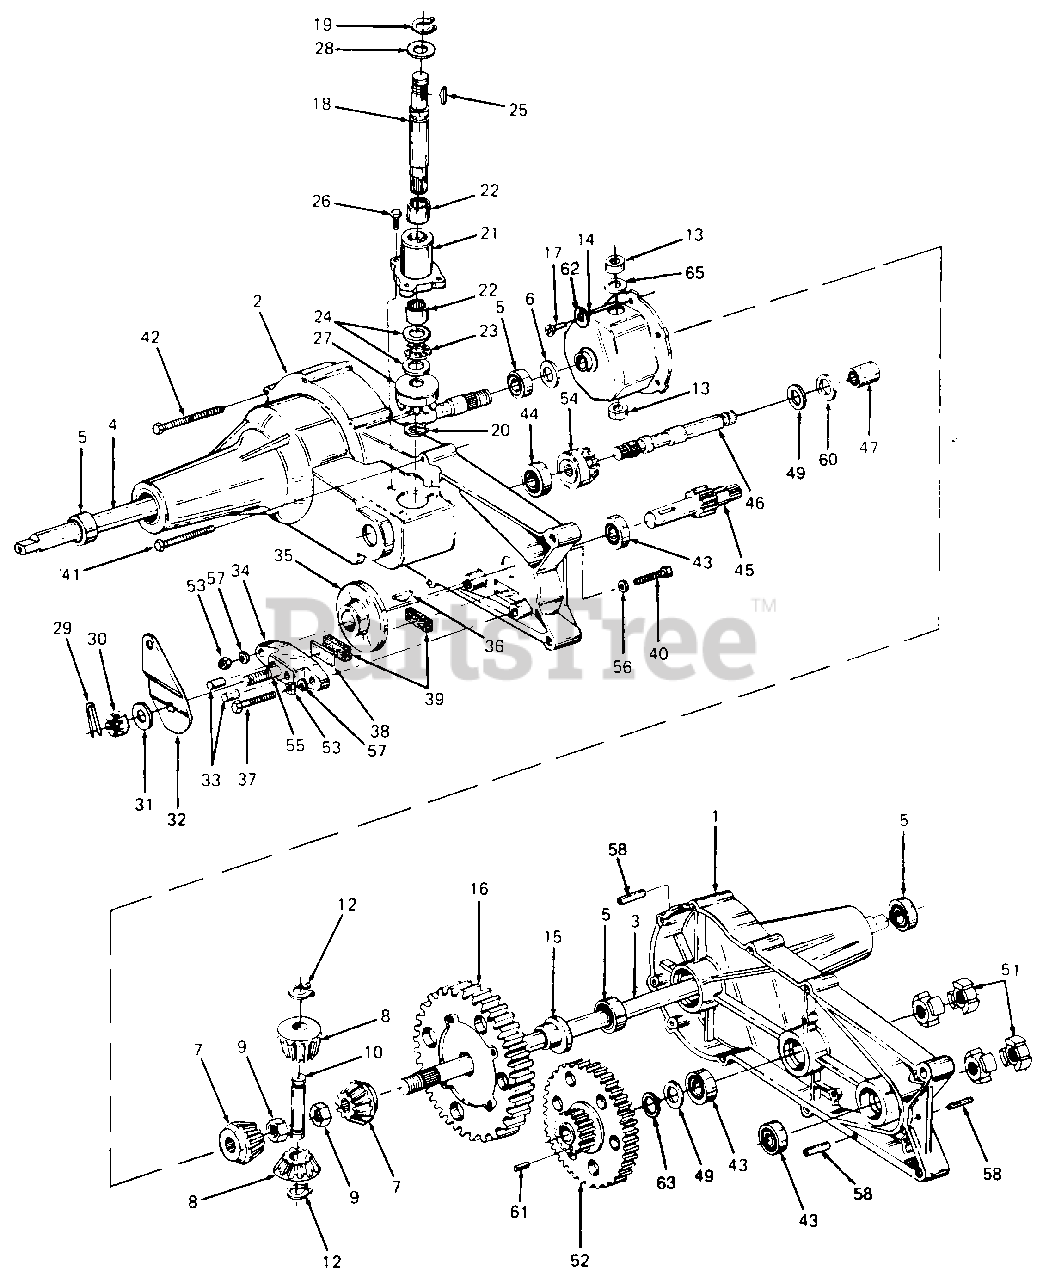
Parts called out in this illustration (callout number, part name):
1	Housing Half, L.H.
2	Housing Half, R.H.
3	Axle, L.H.
4	Axle, R.H.
5	Bearing, Ball
6	Washer, Flat, .76" x 1-1/8" x .306" Thk. Hdn.
7	Gear, Miter
8	Gear, Miter
9	Nut, Hex Jam Patch Lock 1/2-20
10	Shaft, Cross
12	Ring, Snap
13	Bearing, Thrust
14	Housing Ass'y. Differential
15	Bearing, Flange, .75" I.D. x .587"
16	Gear, Differential, 72 Tooth
17	Torx Hd. AB-Tap Scr. 1/4 x .62" Lg.
18	Shaft, Input
19	Ring, Snap
20	Ring, Retaining, Ext. 7/16" Dia.
21	Bearing, Input Housing
22	Bearing, Needle, 5/8" I.D. x .50" Lg.
23	Bearing, Thrust
24	Washer, Flat, 5/8" I.D. x 1.12" O.D. x.030" Thk.
25	Key #4 Hi-Pro, 3/32" x 5/8" Dia. (Hdn.)
26	Screw, Hex Patch Lock, 1/4-20 x 3/4" Lg.
27	Gear, Input Pinion, 17 Tooth
28	Washer, Flat, .62" I.D. x 1.0" O.D. x .030" Thk.
29	Pin, Cotter
30	Nut, Castle, 5/16-24 Thd.
31	Washer, Flat, .343" x .88" x 062" Thk.
32	Arm, Brake Actuator
33	Pin, Actuating, 5/16" Dia.
34	Yoke, Brake
35	Disc, Brake
36	Key, Hi-Pro, 3/16" x 5/8" Dia.
37	Screw, Hex Patch Lock, 1/4-20 x 1.5" Lg.
38	Plate, Puck
39	Puck, Brake
40	Screw, Hex Cap, 1/4-20 x 1.5" Lg.
41	Screw, Hex Self-Tap, 1/4-20 x 2.0" Lg.
42	Screw, Hex Self-Tap, 1/4-20 x 2.75" Lg.
43	Bearing, Ball
44	Bearing, Ball
45	Shaft, Pinion w/11 Tooth Gear
46	Shaft, Drive
47	Bearing, Needle
49	Washer, Flat, 5/8" x 1.12" x .060" Thk.
51	Coupling
52	Gear, Tooth 60 & 17
53	Nut, Hex Jam, 1/4-20 Thd.
54	Gear, Drive Pinion, 17 Tooth
55	Bolt, Square Hd. 5/16-24 Thd.
56	Washer, Flat, .265" x .938" x .12" Thk.
57	Washer, Lock, 1/4" I.D.
58	Pin, Roll, 3/16 Dia. x .50" Lg.
60	Bronze Thrust Brg. 5/8" I.D.
61	Dowel Pin 3/32" x 1/4"
62	Washer, Spring Lock 1/4" I.D.
63	Seal, Grease
65	Washer, Flat, .62" I.D. x 1.0" O.D. x .020" Thk.
